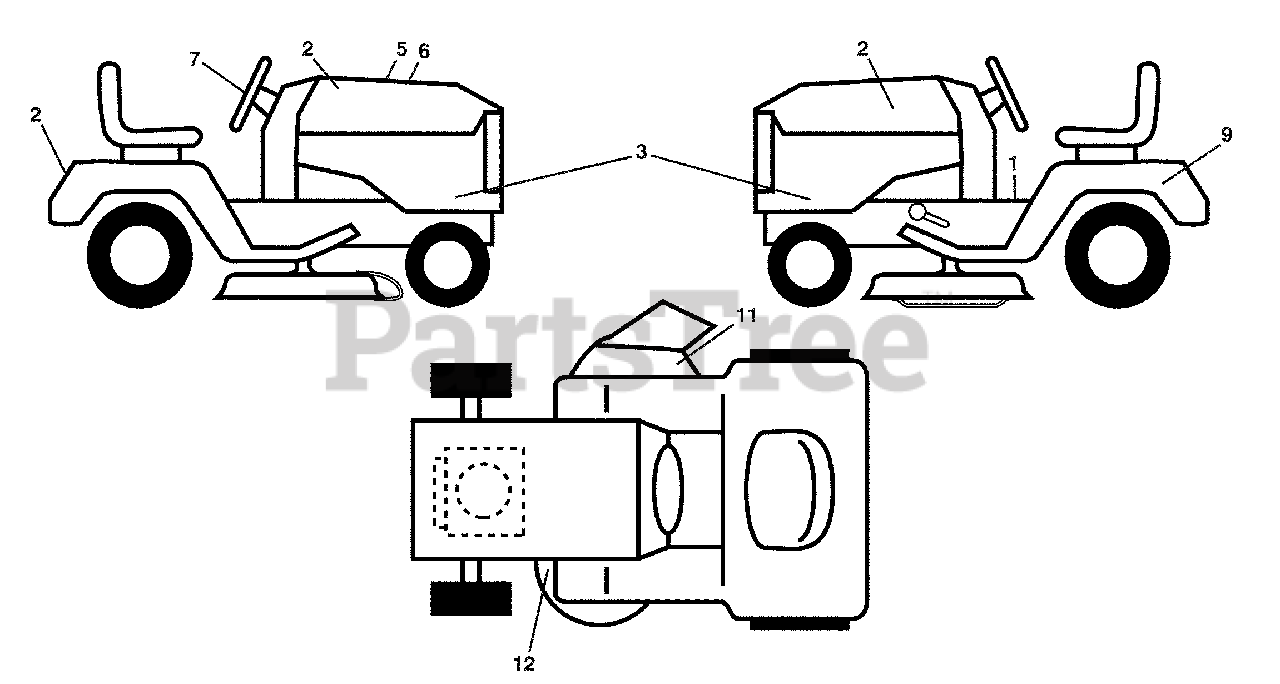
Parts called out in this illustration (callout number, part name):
1	Decal, Warning
2	Decal, Hood
3	Decal, SDPNL
5	Decal, Customer Respons.
6	Decal, Replacement
7	Decal, Steering Wheel
9	Decal, Battery Dnge/Poi
11	Decal, Warning
12	Decal, Mower V-Belt Schematic
